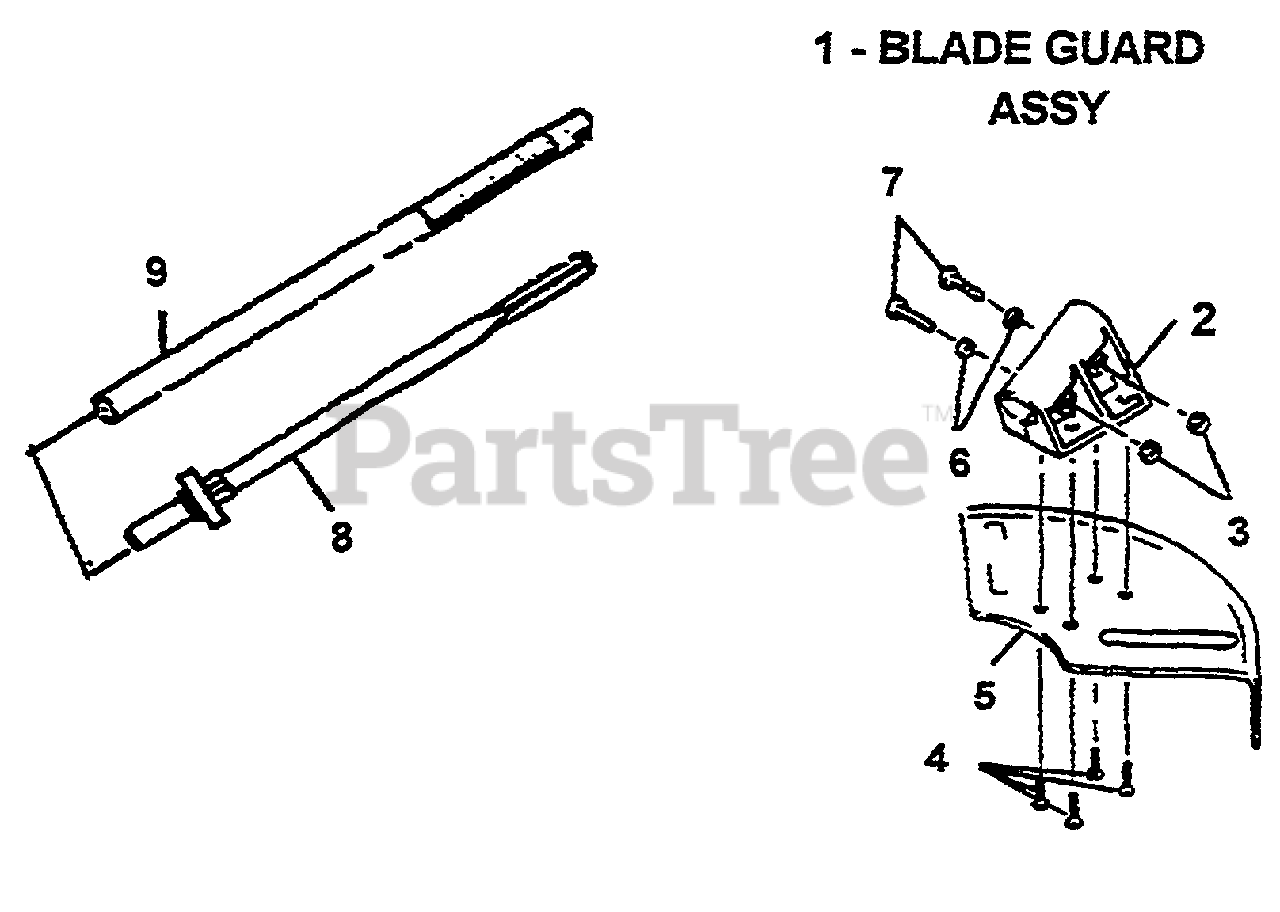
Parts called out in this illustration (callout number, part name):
1	BLADE GUARD ASSY
4	SCREW
5	GUARD
8	FLEX CABLE
9	TUBE ASSY
